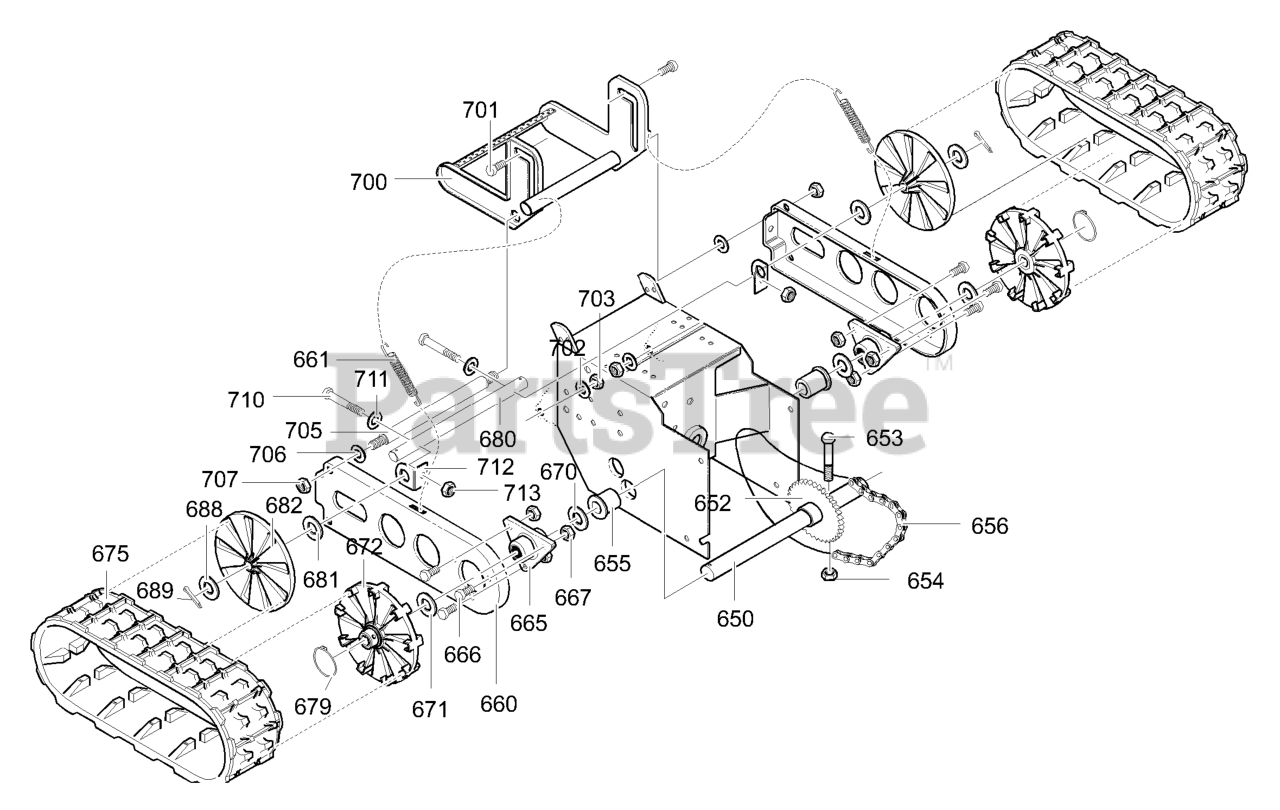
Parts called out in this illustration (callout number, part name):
650	SHAFT, AXLE
652	SPROCKET AND HUB
655	BEARING, FLANGE
656	CHAIN, ROLLER
660	PLATE, TRACK DIRECT
661	SPRING, DRIVE IDLER
665	BEARING, TRACK
670	SPACER
671	WASHER, FLAT
672	SPROCKET, WHEEL
679	PIN, KLIK
680	SHAFT, IDLER
681	WASHER, FLAT
682	WHEEL IDLER
688	WASHER, FLAT
689	PIN, COTTER
700	PEDAL, FOOT
703	NUT
706	WASHER, FLAT
711	WASHER, FLAT
712	BRACKET, TRACK TENSIONER
